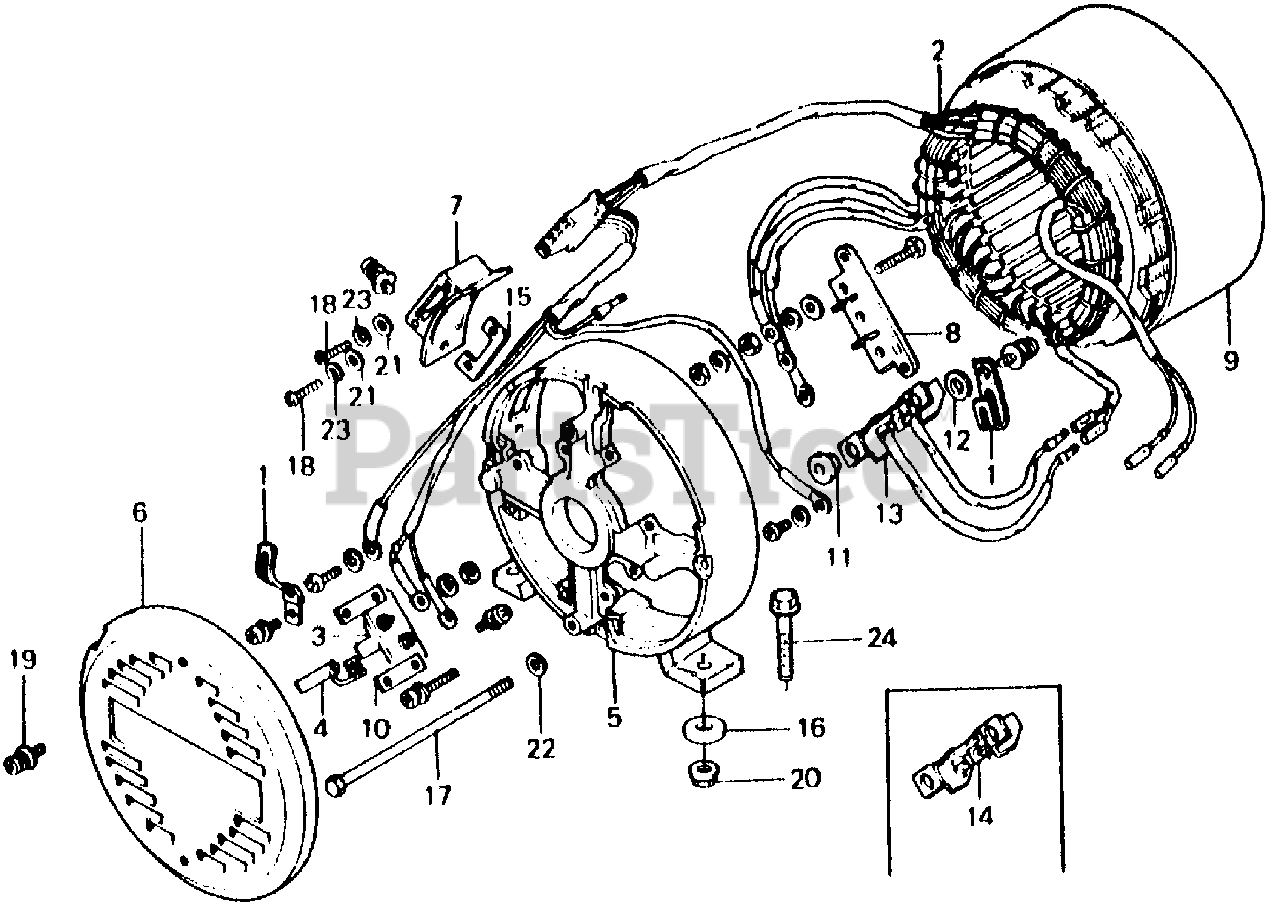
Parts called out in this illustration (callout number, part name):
1	CLAMP B, WIRE
2	STATOR ASSY.
3	HOLDER, BRUSH
4	BRUSH, CARBON
5	HOUSING, RR. *NH31* (MCKINLEY WHITE)
6	COVER, GENERATOR *R8* (BRIGHT RED)
6	COVER, ALTERNATOR END *R8* (BRIGHT RED) (NOT AVAILABLE)
7	COVER, CONNECTOR *NH31* (MCKINLEY WHITE)
8	TERMINAL, VOLT CHANGE
9	COVER, STATOR *NH31* (MCKINLEY WHITE) (NOT AVAILABLE)
10	STAY, BRUSH HOLDER
11	BUSH, INSULATING
12	WASHER, INSULATING
13	DIODE ASSY., D.C. (NOT AVAILABLE)
14	DIODE, D.C.
15	PLATE, CONNECTOR SETTING
16	WASHER, EX. MANIFOLD
17	BOLT, HEX. (6X130)
18	SCREW, PAN (3X10)
19	SCREW-WASHER (5X10)
20	NUT, FLANGE (10MM)
21	WASHER, PLAIN (3MM)
22	WASHER, PLAIN (6MM)
23	WASHER, SPRING (3MM)
24	BOLT, FLANGE (10X32)
